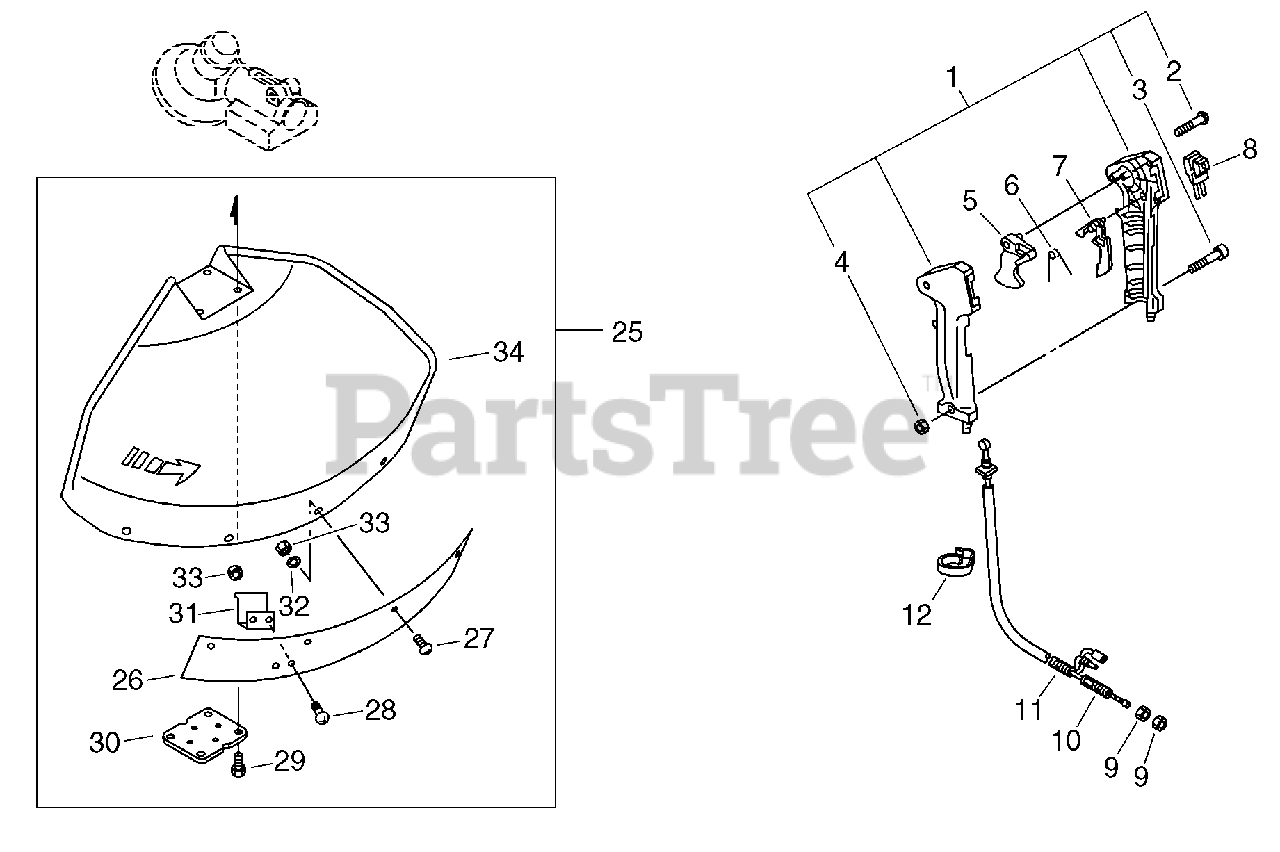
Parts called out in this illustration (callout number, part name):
1	CONTROL HANDLE KIT
2	SCREW 3×25
3	SCREW 5×30
4	NUT M5
5	TRIGGER, THROTTLE
6	SPRING, TORSION
7	LOCKOUT, THROTTLE
8	SWITCH, ON-OFF
10	CABLE, THROTTLE
11	TUBE, FLEXIBLE 7×820
25	DEBRIS SHIELD ASSY
26	EXTENSION, SHIELD
27	SCREW 5×18
28	BOLT 5×14
29	BOLT 5×25
30	PLATE, SHIELD
31	CUTTER, LINE
32	WASHER 5.5×12×0.8
33	NUT M5
34	SHIELD, DEBRIS
